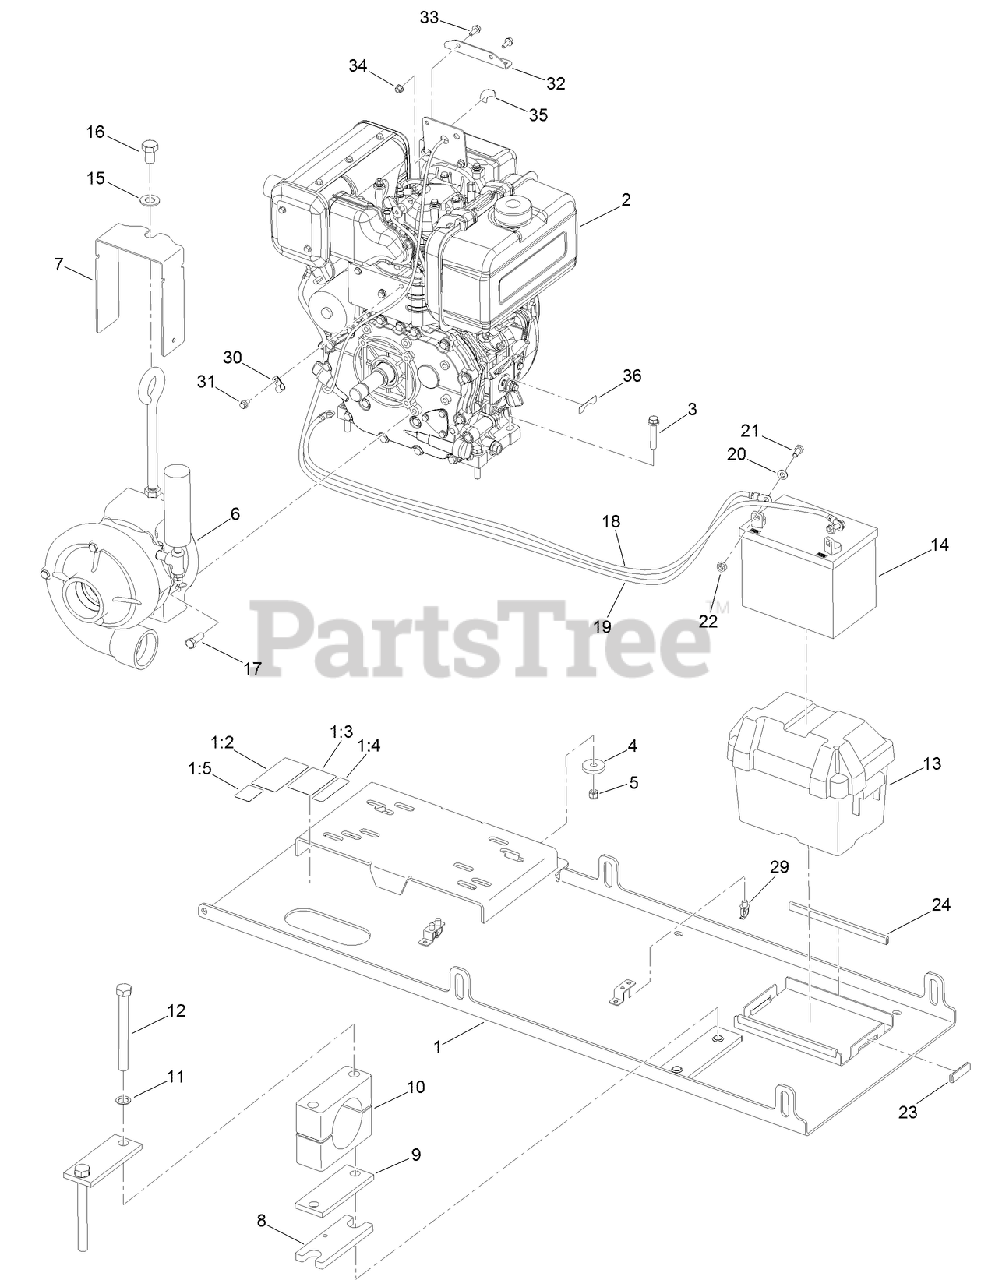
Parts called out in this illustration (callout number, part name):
1	BASE FRAME ASM
1:2	DECAL-WARNING, MIXER
1:3	DECAL-DRAIN
1:4	DECAL-DANGER
1:5	DECAL-ULTRA LOW SULFUR DIESEL
2	ENGINE-YANMAR, L100W
3	SCREW-HHF
4	WASHER-CLUTCH
5	NUT-LOCK
6	PUMP ASM
7	GUARD-COUPLER, ROTATING
9	PLATE-CLAMP
10	CLAMP-PIPE
11	WASHER-FLAT
13	BATTERY BOX ASM
14	BATTERY
15	WASHER-FLAT
16	SCREW-HH
17	SCREW-HH
18	CABLE-BATTERY, NEGATIVE
19	CABLE-BATTERY, POSITIVE
20	WASHER-PLAIN
21	SCREW-HH
22	NUT-HHF, SMOOTH
23	TRIM-STRAP, BATTERY
24	TRIM-TANK
29	CLIP-TIE
30	CLAMP-R
31	SCREW-HHF
32	BRACKET-SWITCH, KEY
33	SCREW-HHF
34	NUT-FLANGE, NI
35	DECAL-IGNITION
36	DECAL-THROTTLE
